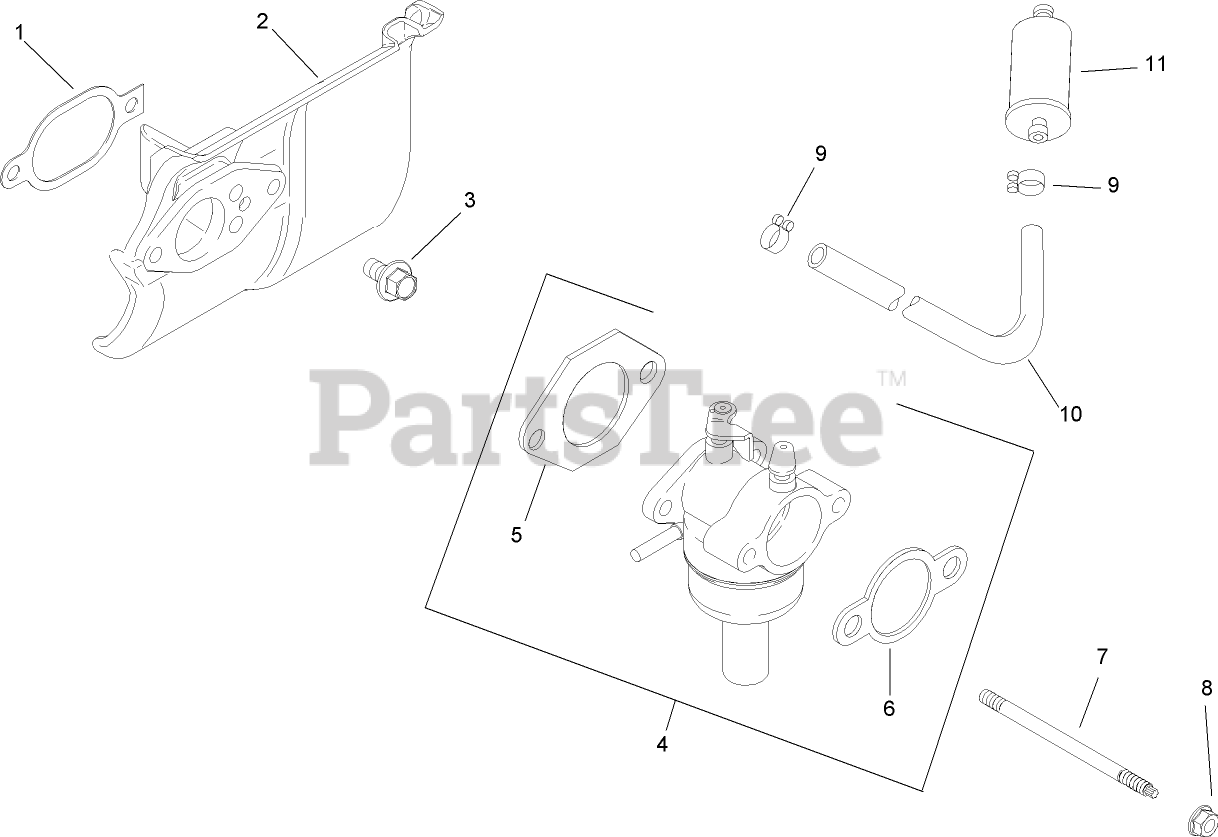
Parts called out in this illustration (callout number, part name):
1	Gasket-Deflector, Heat
2	Deflector-Heat
3	Screw-Flange, Hex (M6x1.0x20)
4	Carburetor ASM w/Gaskets (Includes 5-6)
5	Gasket-Carburetor
6	Gasket-Base, Air Cleaner
7	Stud-Mounting, Carburetor (M6X1.0X100)
8	NUT-FLANGE (M6X1.0)
9	CLAMP-HOSE, SPRING (1/2)
10	Line-Fuel, 7 Inch (filter to carb)
11	FILTER-FUEL
12	Washer-Lock, Internal Tooth (1/4)
13	Choke Shaft Kit
14	Float Repair Kit
15	Carburetor Repair Kit
16	Solenoid Repair Kit
17	Bowl Replacement Repair Kit
18	Tie-Wire
